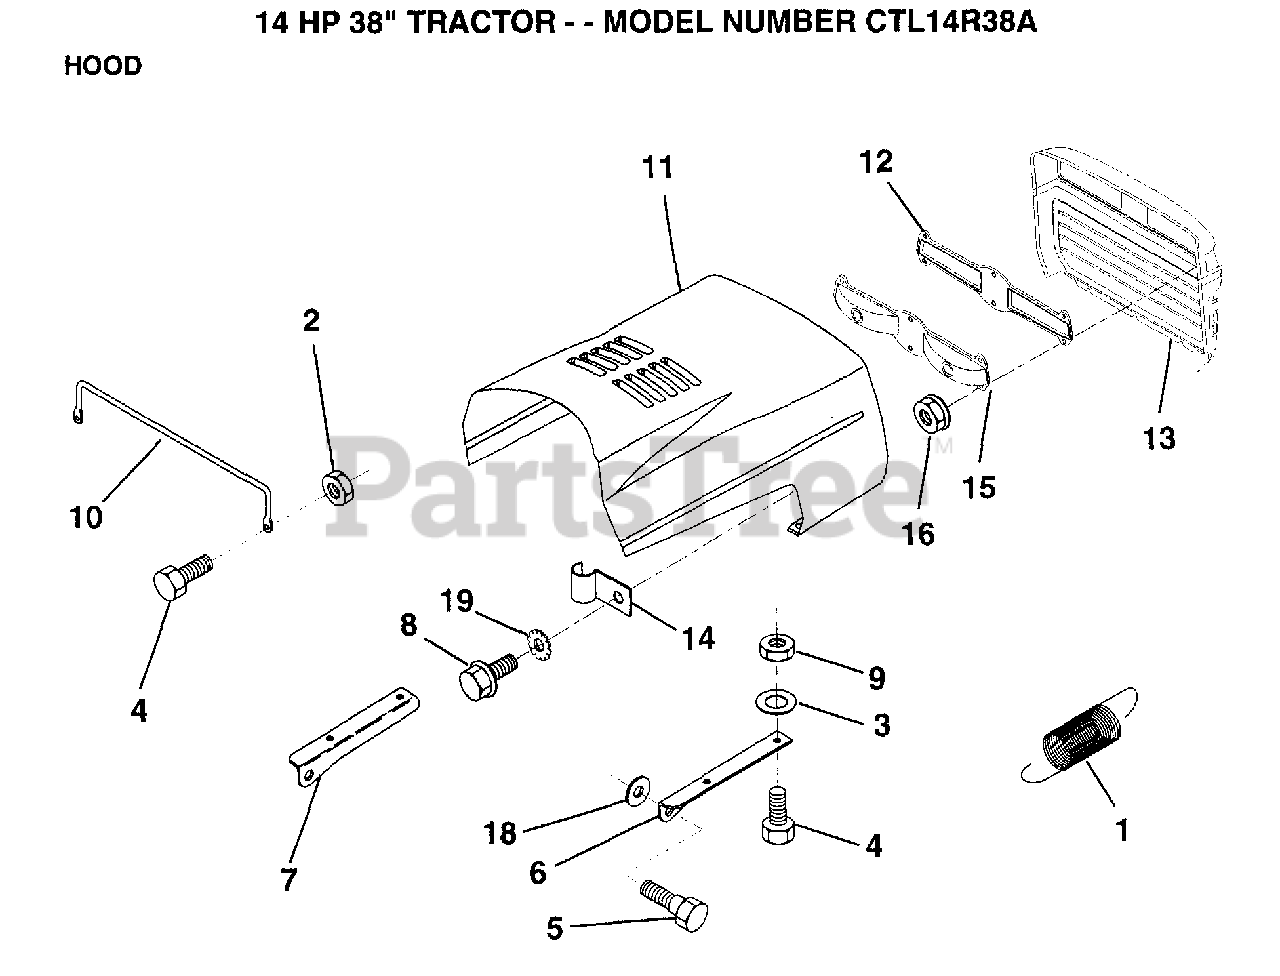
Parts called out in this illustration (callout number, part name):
1	EXT SPRING
2	NUT
3	WASHER
6	BRKT HOOD RH
7	BRKT HOOD LH
9	NUT
10	"BRACE,HOOD"
11	HOOD
13	GRILL (BLACK)
16	NUT
18	WASHER
19	LOCKWASHER GT
